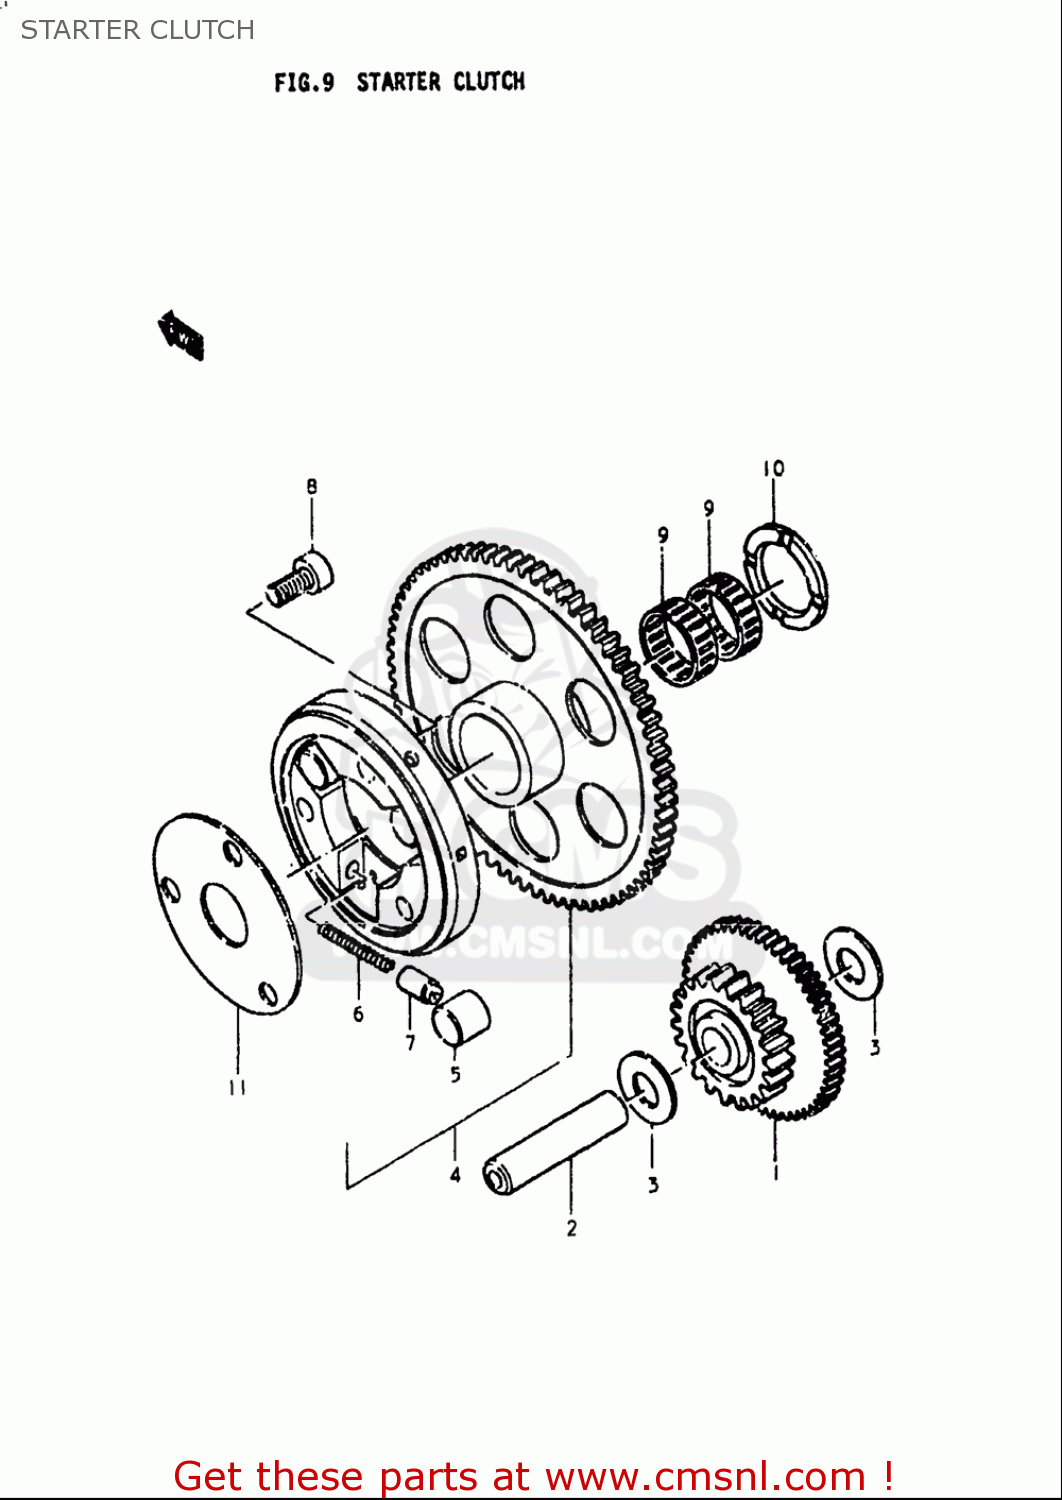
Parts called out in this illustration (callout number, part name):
2	PIN(7.4X13X56)
3	WASHER(13.3X25X0.85)
4	CLUTCH SET,STARTER
5	ROLLER(15X13)
6	SPRING
7	PIECE,PUSH
8	BOLT
9	BEARING(25X29X9.9)
10	WASHER(25X38X2.5)
11	SHIM,STARTER CLUTCH HUB
